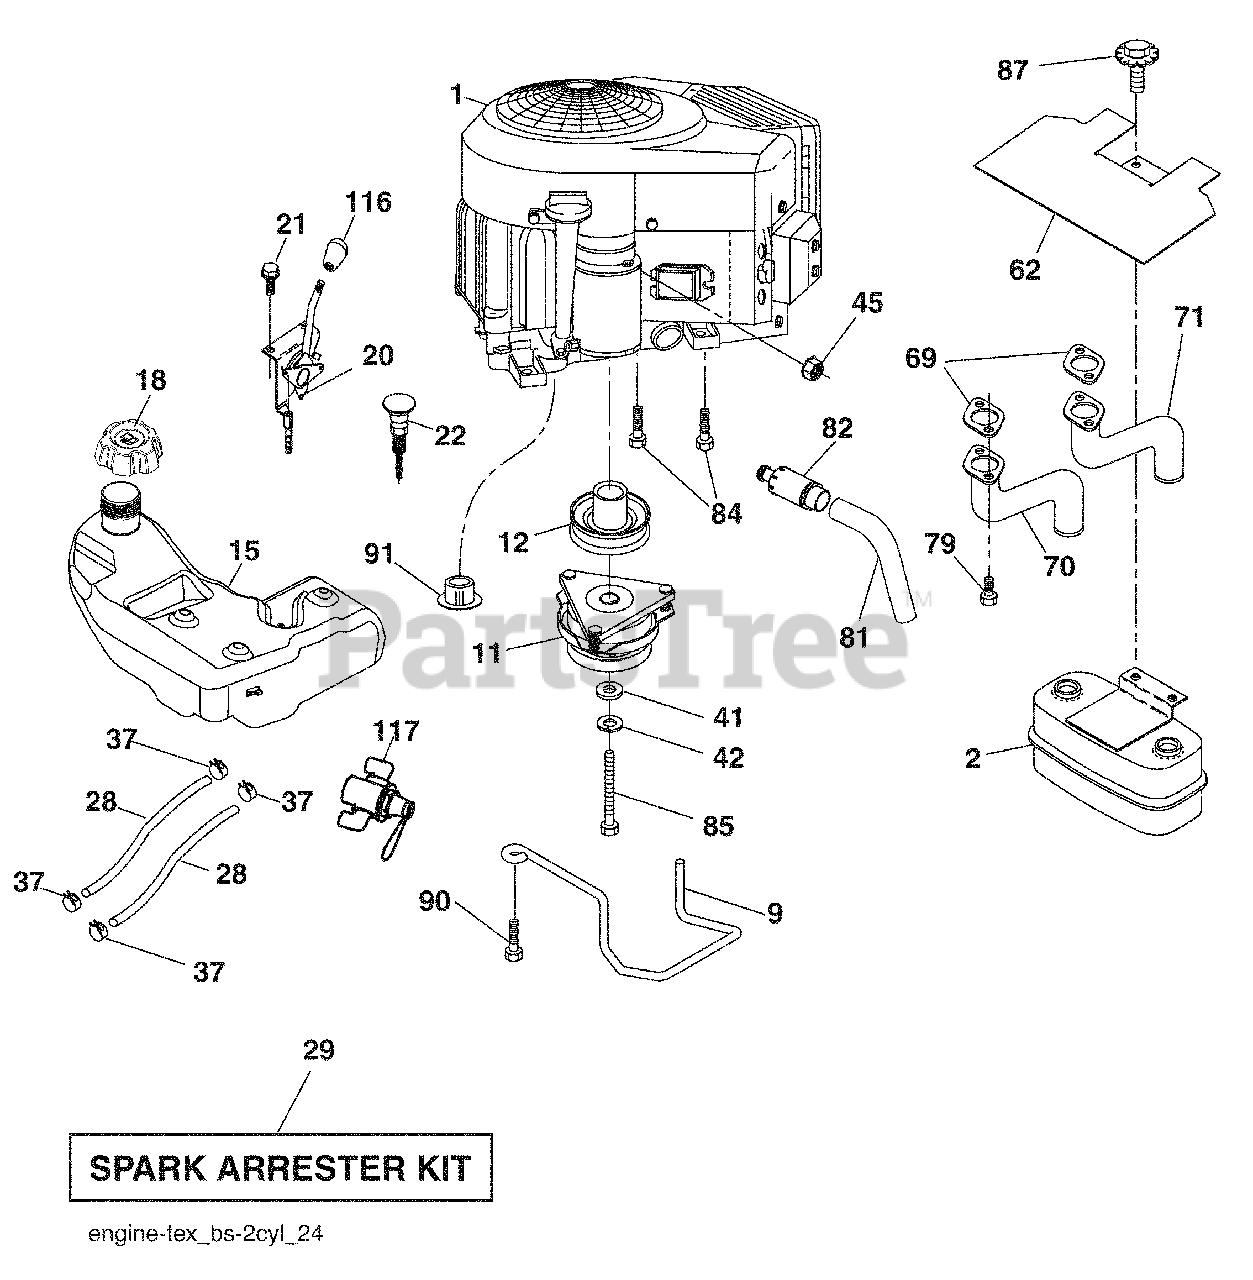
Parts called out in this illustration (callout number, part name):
9	Keeper Belt Engine
11	Clutch
12	Pulley Engine
18	Cap Asm
20	Control Throttle
21	Screw #10 x .750 BOS Thread
28	Fuel Line
29	Spark Arrester Kit
37	Clamp Hose
41	Washer 1-1/2 OD x 15/32 ID x .250
42	Washer Lock 7/16
45	Nut Keps Hex 1/4-20 unc
62	Heat Shield
70	Exhaust Tube LH
71	Exhaust Tube RH
79	Screw Tube Muffler
81	Tube Drain Oil Easy
82	Plug Drain Oil
84	Screw 3/8-16 x 1-1/4
85	Bolt Hex 7/16-20 x 4 x Gr. 5-1.5 Thr
87	Bolt 5/16-18 unc x 3/4 w/Sems
90	Screw 3/8-16 x 1
116	Knob Soft Touch
117	Fuel Valve
